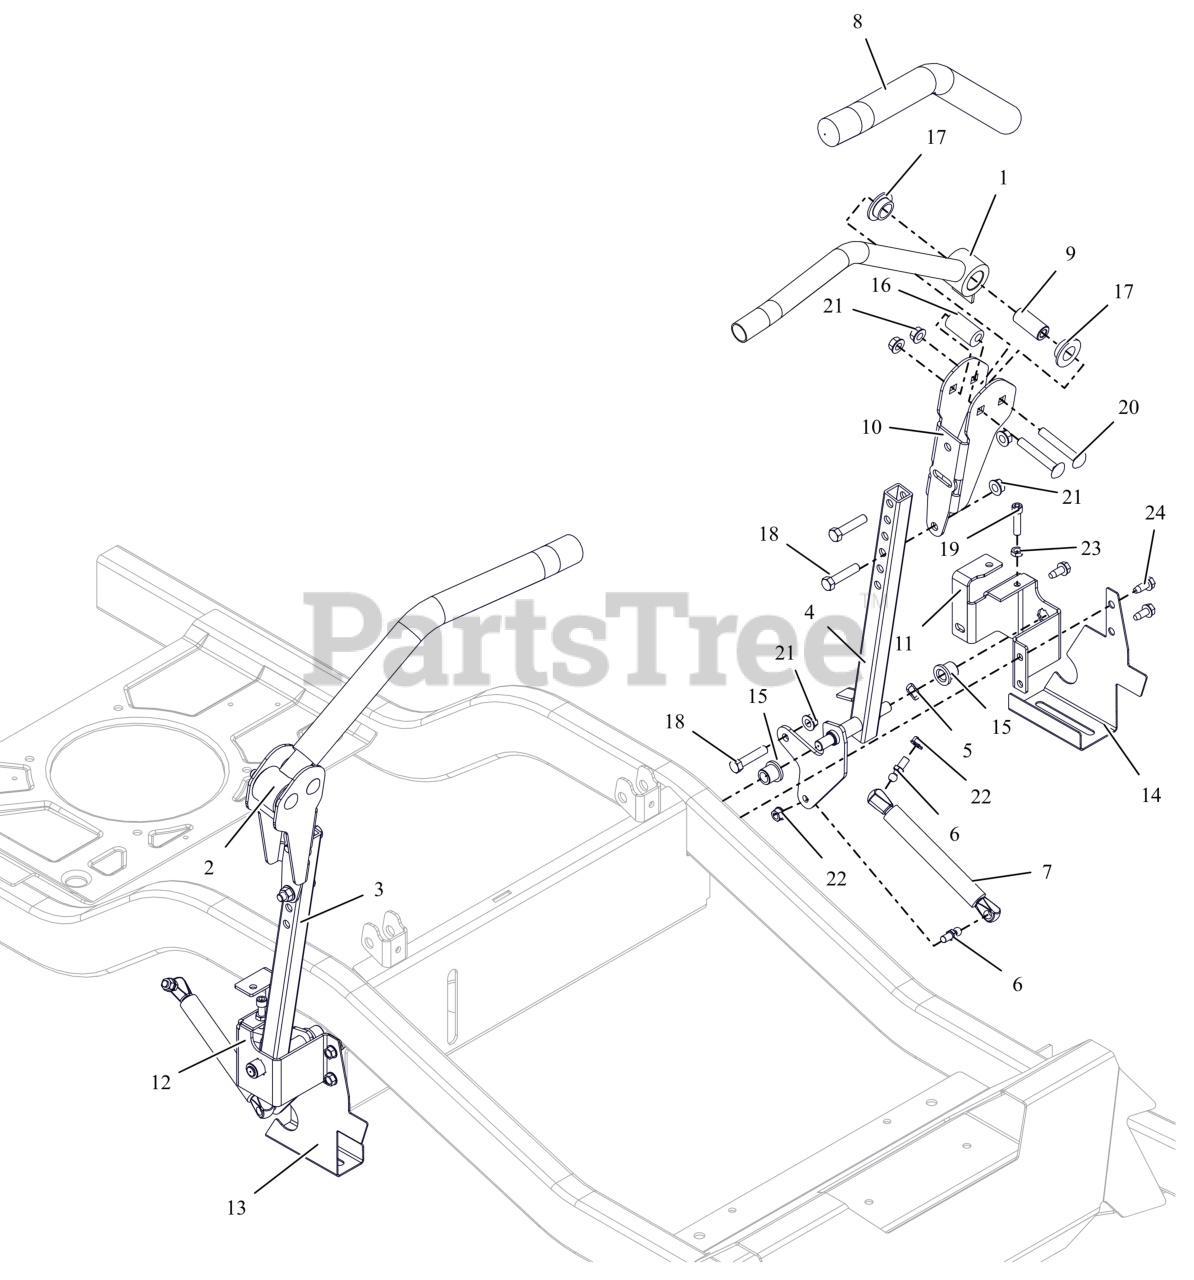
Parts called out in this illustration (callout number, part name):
1	WLDMT, CONTROL HANDLE- BLK
2	WLDMT, CONTROL HANDLE- BLK
3	WLDMT, STEERING RH
4	WLDMT, STEERING LH
5	WAVE WASHER .531X.781X.125FH
6	STUD- BALL
7	DAMPER
8	GRIP, HANDLEBAR
9	SPACER, STEERING ARM
10	ADJ UPPER CONTROL ARM BRKT-BLK
11	BRKT, STEERING ARM MOUNT -LH
12	BRKT, STEERING ARM MOUNT -RH
13	GUARD, FRAME RAIL BELT RH
14	GUARD, FRAME RAIL BELT LH
15	BHSG-FLG .500X.750X.750X.125
16	BSHG, ECCENTRIC.406X.875X1.625
17	BSHG-FLG .762X1.48X.44 NYL
18	BLT, HEX .38-16X1.75 G5 ZCC
19	BLT, SHCS .312-18X1.25 G8 SS
20	BLT, RHSSN.38-16X2.50 G5 ZCC
21	NUT-LK-TOP-FLG .38-16 ZC120
22	NUT,LK-CTR-FLG .31-18 GF ZCC
23	NUT-JAM .312-18 G2 ZCC
24	SCR,TAP .312-18X.75 HWH TR ZCC
